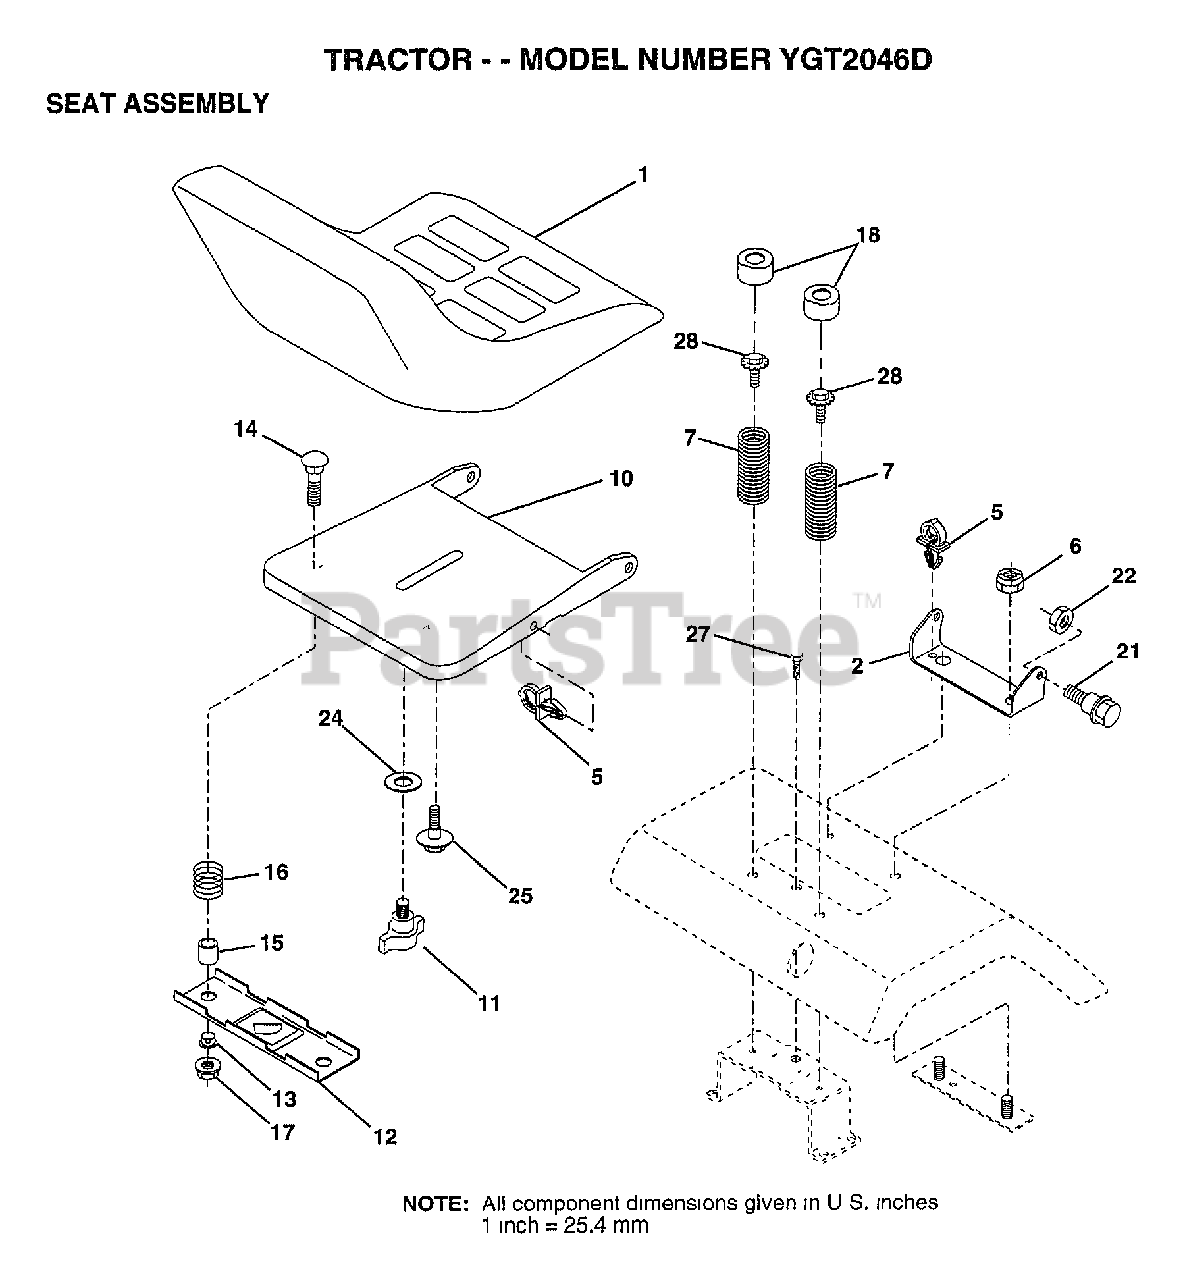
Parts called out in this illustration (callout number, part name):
2	BRACKET PVT SEAT
5	CLIP.PUSH-IN.HING
6	NUT
7	SPRING COMPRESSIO
10	PAN-SEAT
11	KNOB.SEAT.ADJ.WINGNUT
12	BRKT SWITCH
13	BUSHING
14	BOLT-RD HD SQ NK
15	SPACER SPLIT
16	SPRING COMPRESSED
18	CAP SPRING
21	"BOLT,SHOULDER"
24	WASHER
25	"BOLT,SHOULDER"
27	SCREW LT
28	BOLT.5/16-18.UNC
